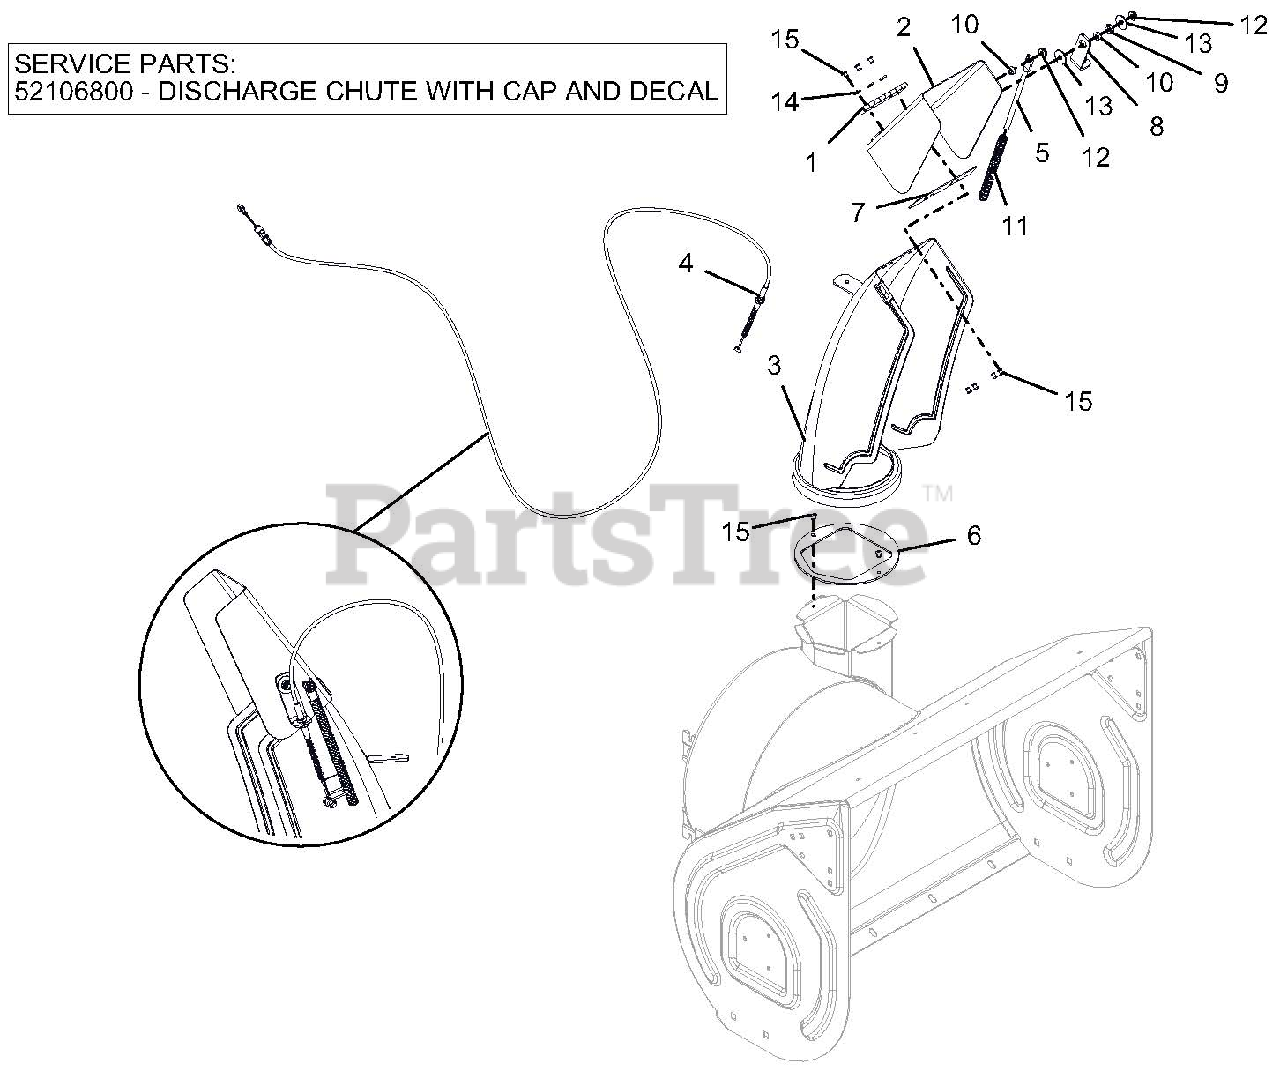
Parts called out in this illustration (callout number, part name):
2	CAP,LARGE,REMOTE
3	CHUTE,DISCHARGE,NOTCHED,QT
4	CABLE, DEFLECTOR - DELUXE
5	ROD, DEFLECTOR CAP
6	BAFFLE, DISCHARGE NECK
7	CAP SEAL 5.50
8	BRACKET, CABLE ANCHOR
9	BUSHING, POLYLINER-.50 SNAPIN
10	BSHG-SLV .265X.500X.219
11	SG-COMP .08X.40X6.50 14#/IN
12	@NUT-LK-CTR-FLG .25-20 YWZC
13	WSHR-FL-STL .281X1.000X.063
14	WSHR-FL-STL .196X.500X.06 YZ
15	RVT-POP .187 YZ
16	KIT, DISCHARGE CHUTE W/DEF QT2
